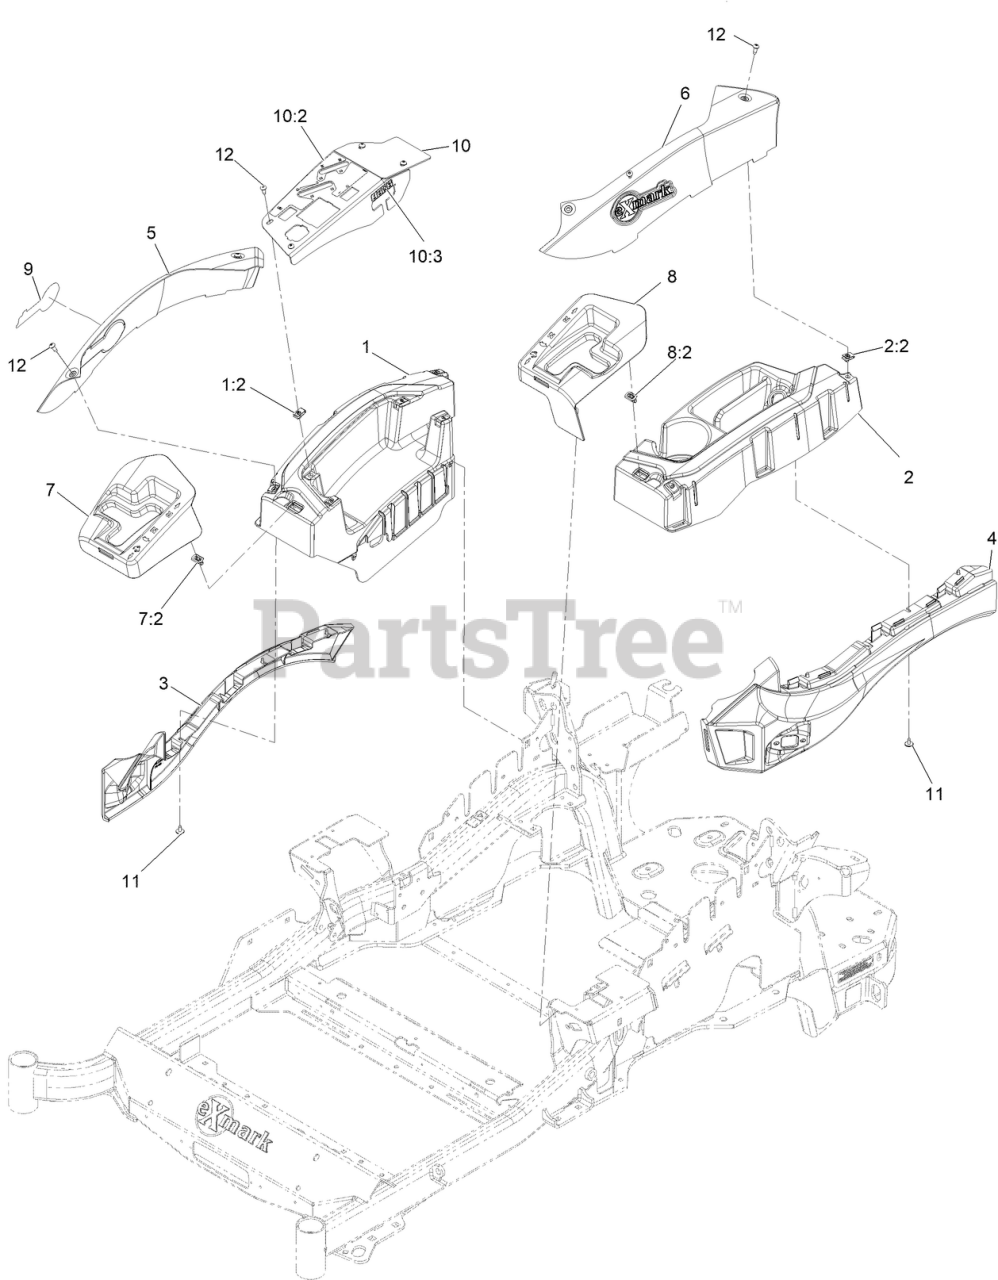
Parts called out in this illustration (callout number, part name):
1	CONSOLE-RH
2	CONSOLE-LH
3	FENDER-RH
4	FENDER-LH
5	PANEL-SIDEPOD ACCENT
6	PANEL-SIDEPOD ACCENT
7	ASM-MOTION CONTROL COVER RH
7:2	Clip-Trim
8	ASM-MOTION CONTROL COVER LH
8:2	Clip-Trim
9	DECAL-EXMARK LOGO
10	ASM-CONSOLE PANEL W/ DECALS
10:2	DECAL-CONTROL PANEL CARB
10:3	DECAL-FUSES
11	SCREW-TORX
12	SCREW-TPH THD FORM
